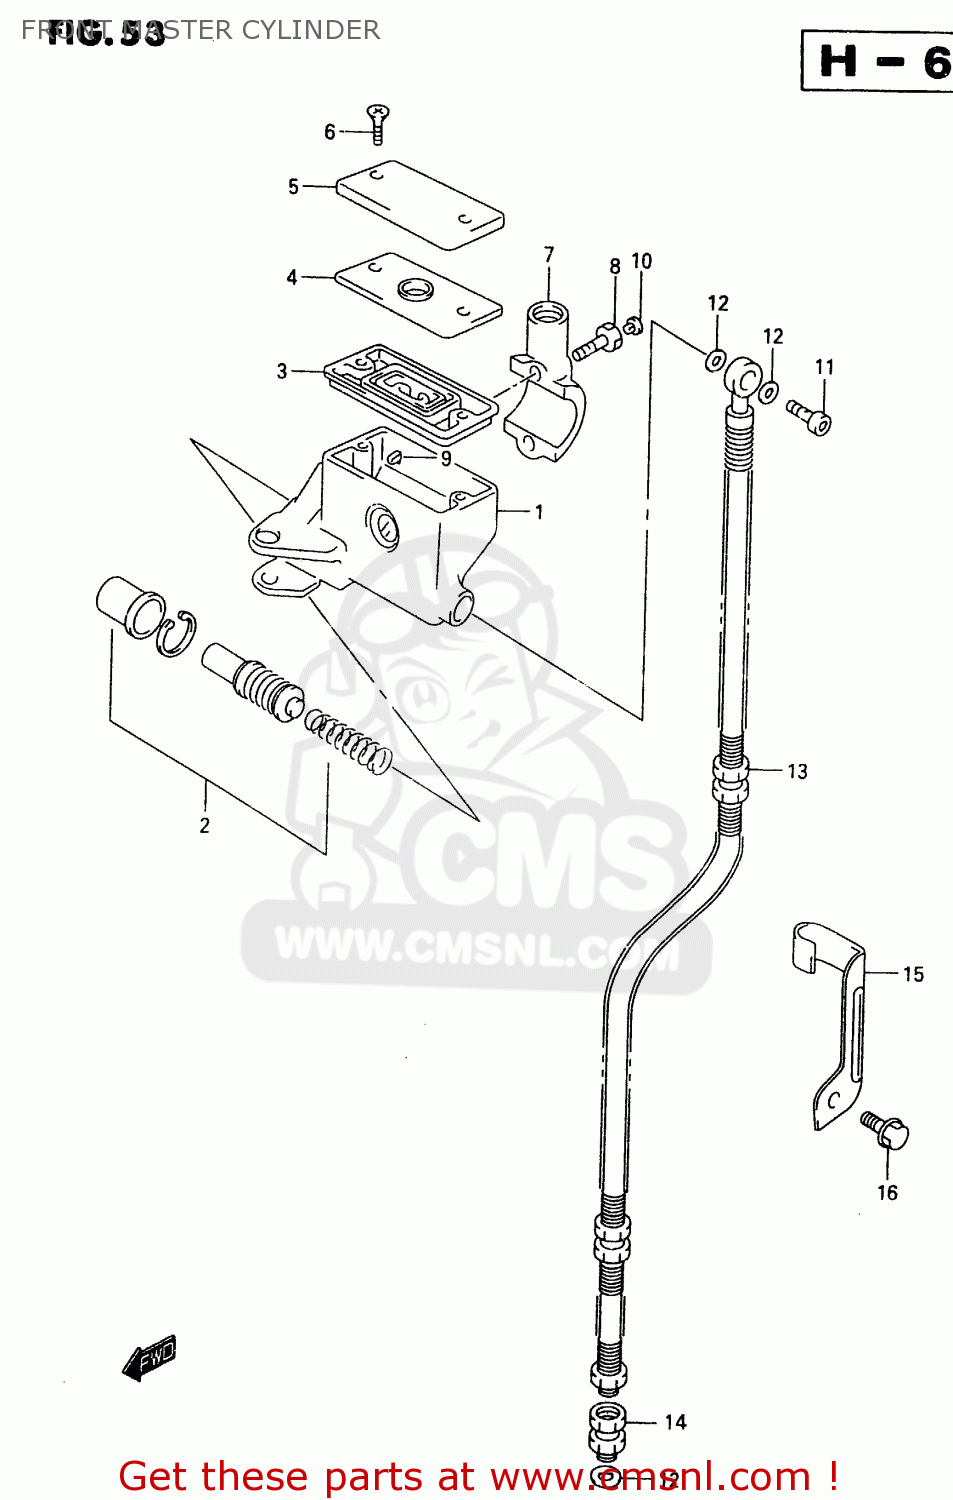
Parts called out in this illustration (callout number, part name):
1	CYLINDER ASSY,FR MASTER
2	PISTON/CUP SET
3	4
4	PLATE,DIAPHRAGM
5	CAP
6	SCREW
7	HOLDER
8	BOLT
9	PROTECTOR
10	CAP(OD:10)
11	BOLT UNION
12	WASHER(10X15X1.5)
13	HOSE,FR BRAKE
14	ADAPTER,BRAKE HOSE
15	CLAMP,FR BRAKE HOSE
16	BOLT
